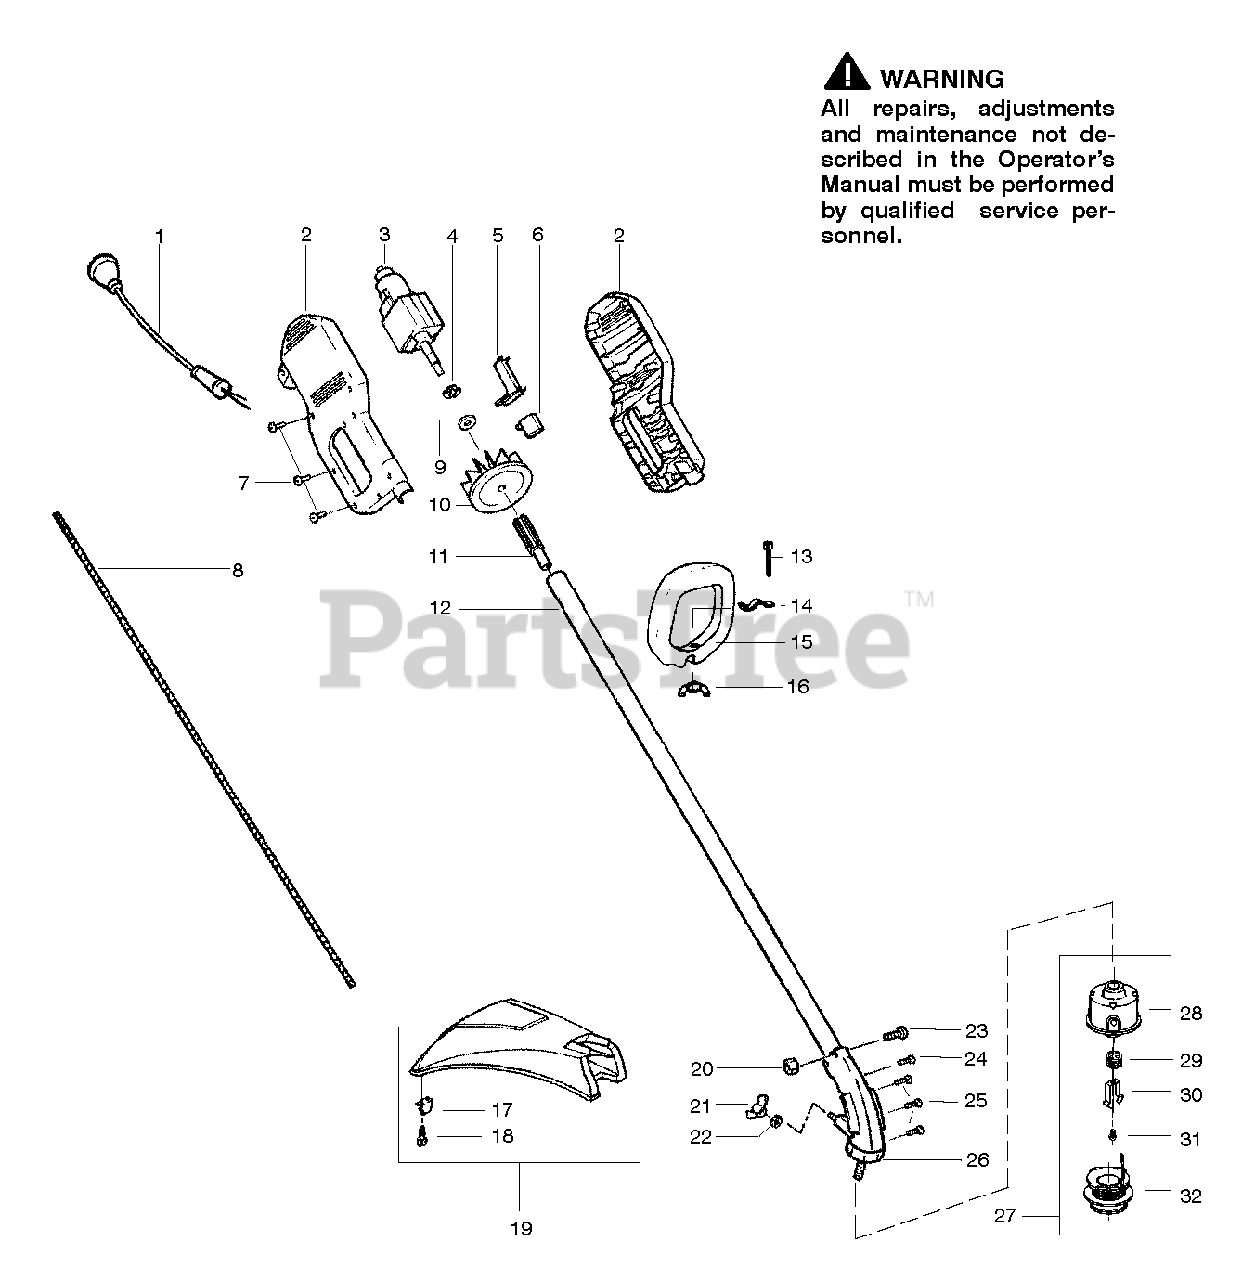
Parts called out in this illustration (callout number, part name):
1	Assy-Wiring Harness
2	Housing Set
4	Retainer-Clip
5	Trigger Switch
8	Flex Shaft
9	Washer-Drive Adaptor
11	Assy-Drive Adaptor
12	Assy-Tube
14	Clamp-Assist Handle
15	Handle-Assist
16	Wingnut
17	Line Limiter
18	Screw-Line Limiter
19	Kit-Shield Ass'y.
24	Screw-Alignment
26	Assy-Gear Box
27	Accy-Cutting Head Ass'y.
28	Kit-Hub Assy.
30	Retainer-Clip
31	Screw w/ Washer-Head
32	Spool w/Line
